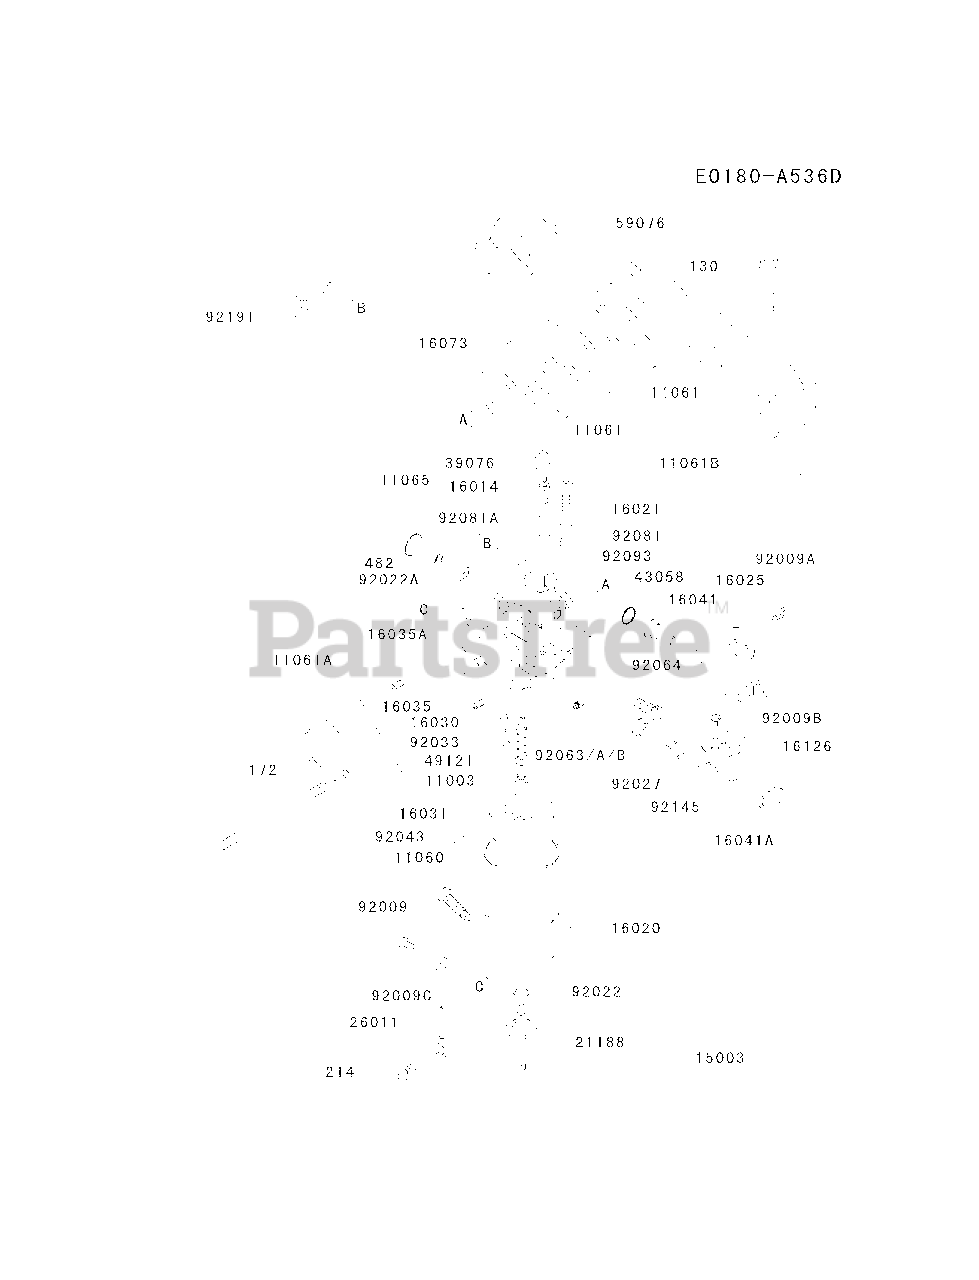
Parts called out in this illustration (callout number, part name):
130	BOLT-FLANGED,6X35
172	BOLT-STUD,6X85
214	SCREW-PAN+-,5X10
482	CIRCLIP-TYPE-E,4MM
92191	TUBE,4.76X7.94X225
